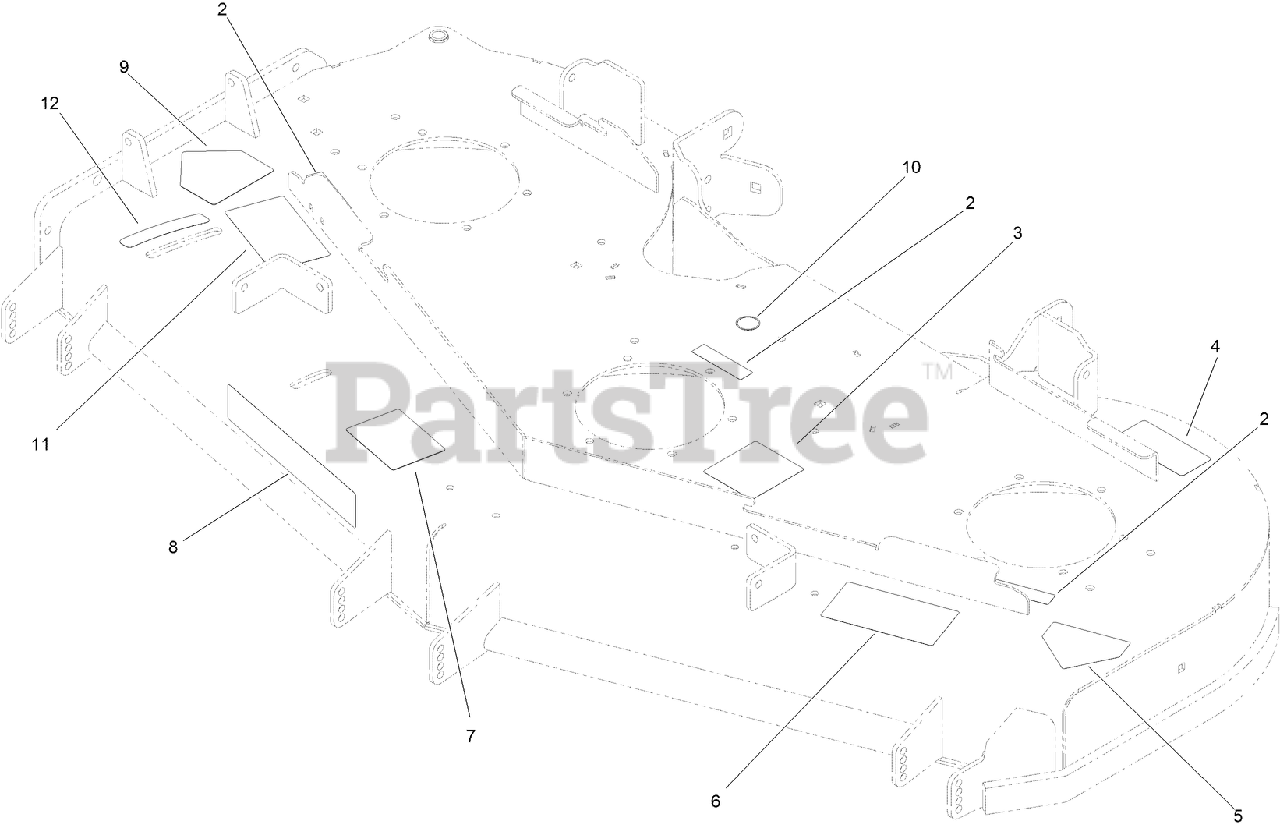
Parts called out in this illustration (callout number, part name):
2	DECAL-COVER, MISSING
3	DECAL-ROUTING, DECK BELT
4	DECAL-TORQUE
5	DECAL-DANGER
6	DECAL-DANGER, THROWN OBJECT
7	DECAL-SCALP, ANTI
9	DECAL-DANGER
10	DECAL-GREASE
11	DECAL-ADJUSTMENT, BAFFLE
12	DECAL-SETTING, BAFFLE
